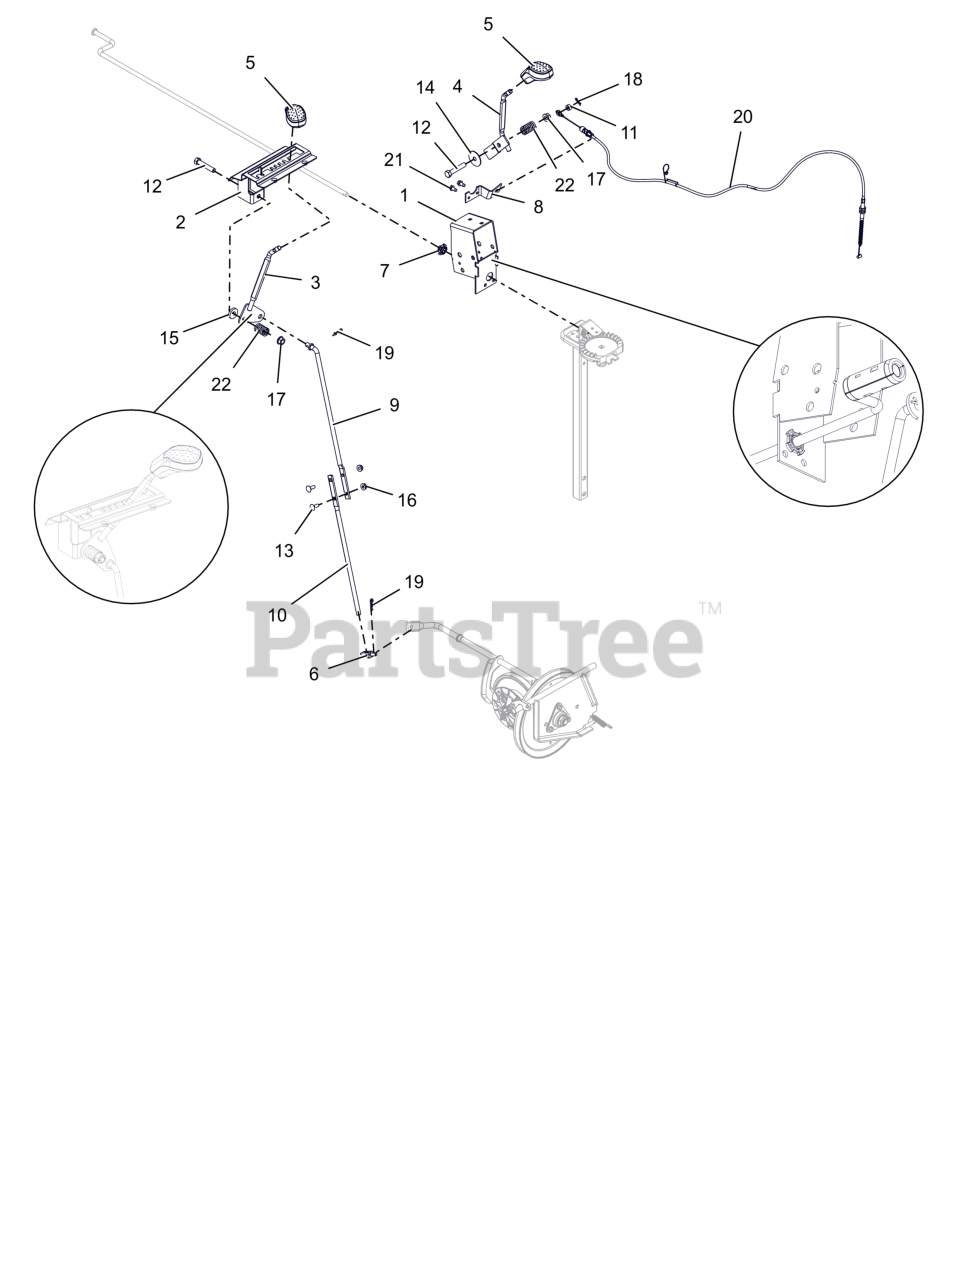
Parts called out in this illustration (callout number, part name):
1	WELDMENT, BRACKET INTERLOCK
2	WELDMENT, DETENT PLATE-COMPACT
3	LEVER, CONTROL-SHIFT(WELDMENT)
4	WELDMENT,SM DASH DEFL CONTROL
5	KNOB, CONTROL, DASH
6	PIVOT,SHIFT ROD .375-16(TRUNN)
7	CRANK BUSHING, NYLON CHUTE BK
8	ANCHOR, DEFLECTOR CABLE
9	ROD, SHIFT UPPER
10	ROD, SHIFT - LOWER
11	BSHG-SLV .265X.500X.219
12	BLT,HEX .38-16X2.00 G5 ZCC
13	BLT, RHSN .25-20X.750 G5 ZCC
14	WSHR,FLT .380X1.50X.062 ZCC
15	WSHR, FLT .406X1.00X.188 ZCC
16	NUT-LK-CTR-FLG .25-20 ZC120
17	NUT-LK-TOP-FLG .38-16 ZC120
18	PIN, HAIR #178 .06X.77 ZCC
19	PIN, HAIR #213 .08X1.19 ZCC
20	CABLE, DEFLECTOR - COMPACT
21	SCR-TAP .25-20X.50 HWH ZCC
22	SG-COMP .125X.781X1.250
